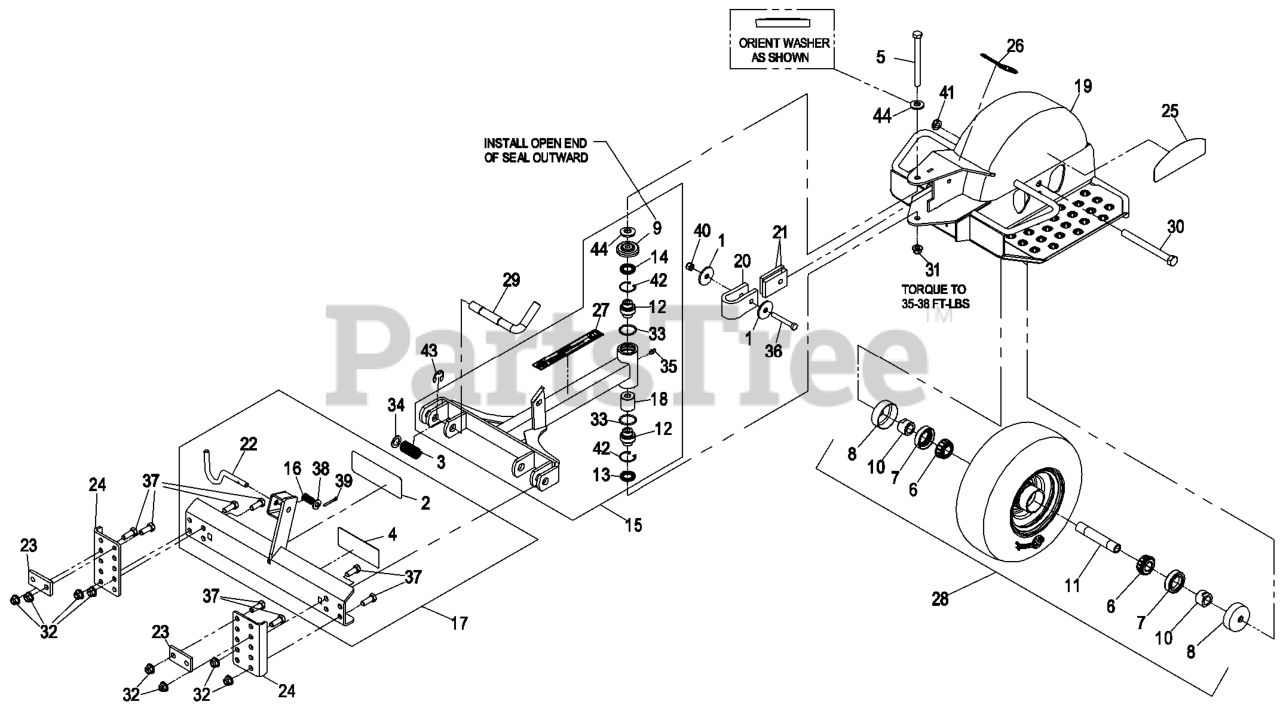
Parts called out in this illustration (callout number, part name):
2	DECAL,BELT DRIVE
3	SPRING,HITCH RELEASE
4	DECAL,SULKY WARNING
5	SCREW-HH
6	BEARING-CONE, TAPERED ROLLER
7	SEAL-CASTER
8	GUARD-SEAL
9	GUARD-TOP
10	SPACER-NUT
12	BEARING-SPHERICAL
13	SEAL-LIP, DOUBLE
14	SEAL-LIP, SINGLE
15	ASM,PULL ARM W/BRGS-DECAL
16	SPRING,LOCK PIN
17	ASM,PULL FRAME
18	SPACER-HYDRO CONTROL, LH
19	ASM,SULKY FRAME W/DECALS
21	PAD,STOP
22	PIN LATCH
23	PLATE,BACK-UP (PLATED)
24	PLATE,ADAPTER
25	DECAL,STANDON
26	DECAL,EXMARK
27	DECAL,SULKY
28	ASM,WHEEL AND BEARING
29	PIN,PULL ARM (PLATED)
30	SCREW-HH
32	NUT-HF, NI
34	WASHER-FLAT
35	FITTING-GREASE
36	SCREW-HH
37	SCREW-HH
38	WASHER-FLAT
39	PIN-COTTER
40	NUT-LOCK, NI
41	NUT-HEX
42	RING-SNAP
44	WASHER-BELLEVILLE
